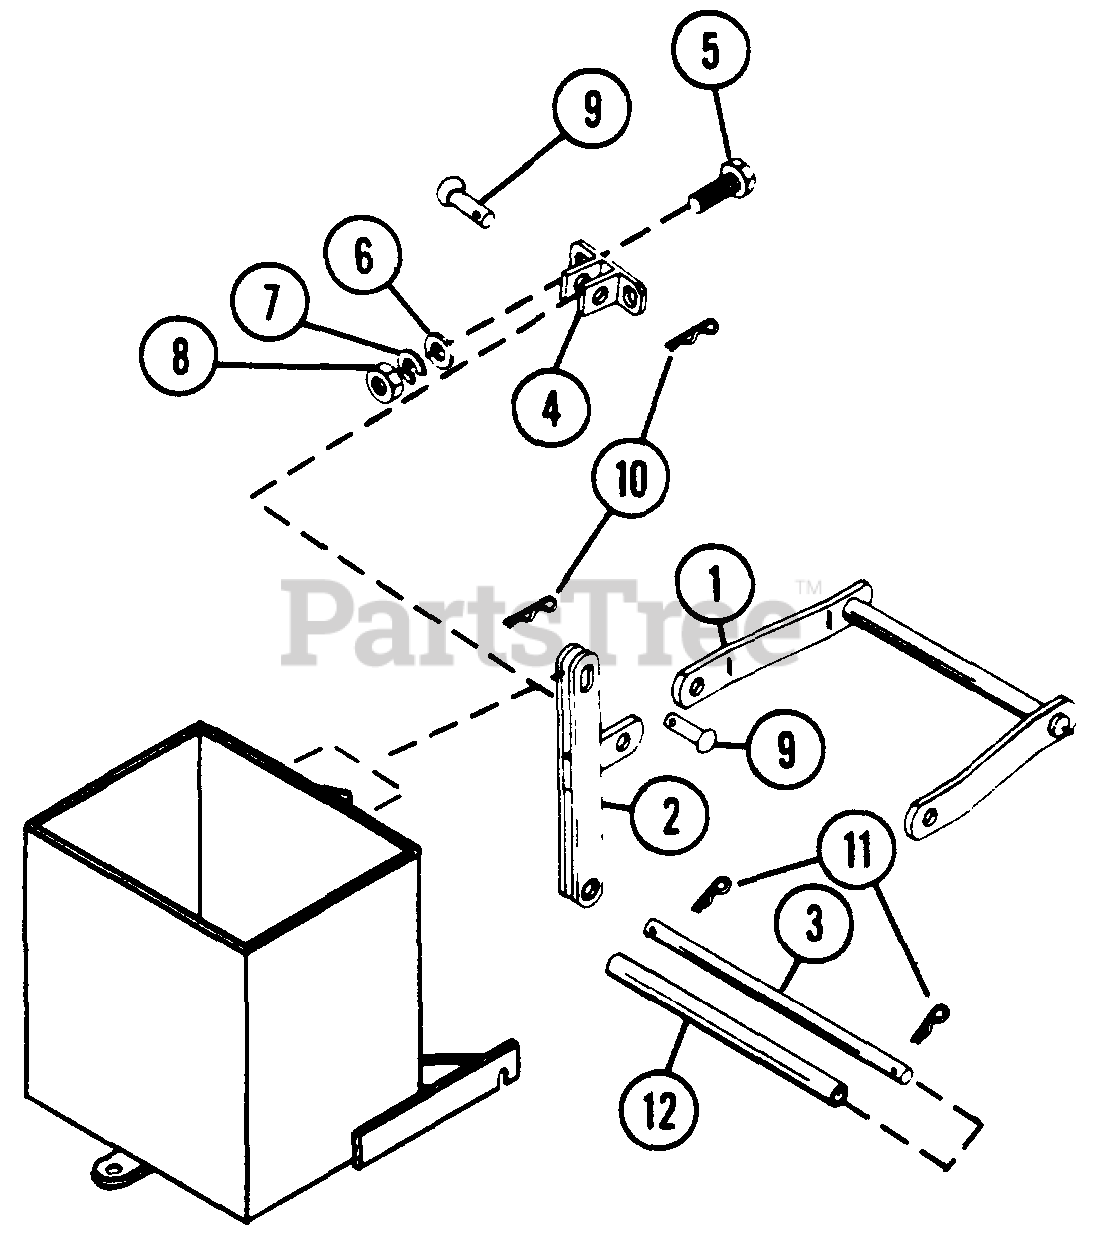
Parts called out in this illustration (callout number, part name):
1	WEIGHT BOX HANGER
2	BOX SUPPORT
3	SHAFT
4	PLATE
5	BOLT, HEX 3/8-16X1.00
6	WASHER, FLAT .438X1.000X.083
7	WASHER, FLAT 3/8 REG.
8	NUT, HEX 3/8-16
9	PIN, CLEVIS
10	PIN, HAIR
11	HAIRPIN, INTERNAL
12	TUBE
NS	DECAL, AMERICA
